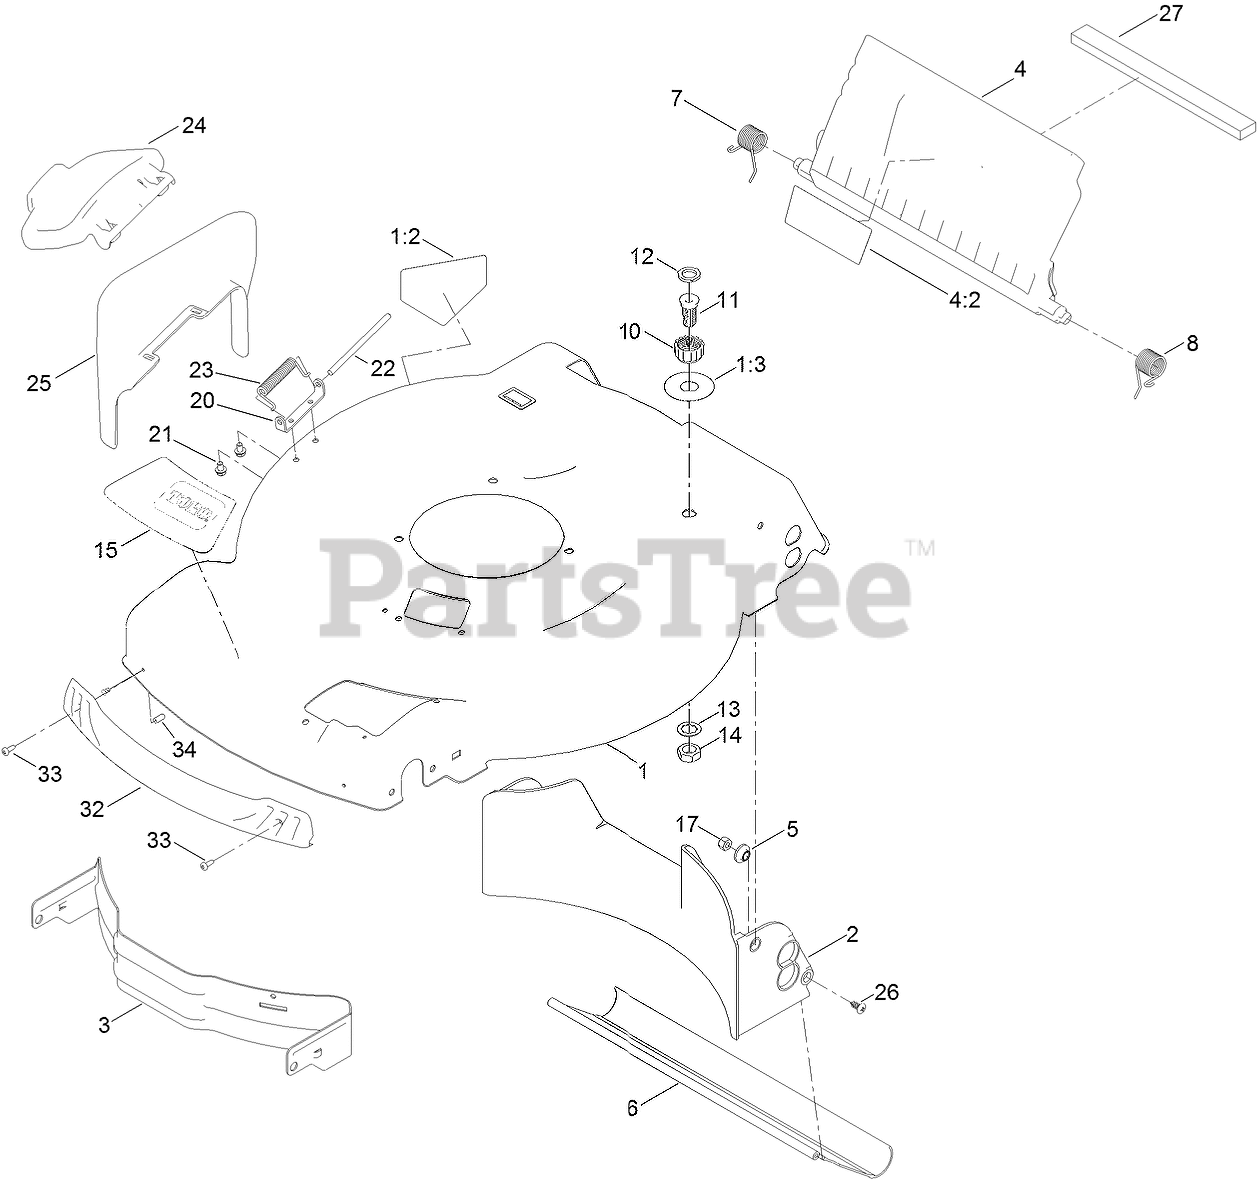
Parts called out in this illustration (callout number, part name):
1	HOUSING ASM
1:2	DECAL-DANGER
1:3	DECAL-QUICK WASH
2	BAFFLE-REAR
3	BAFFLE-FRONT
4	REAR DEFLECTOR ASM
4:2	DECAL-WARNING
5	WASHER-STEPPED, BAFFLE
6	SHIELD-TRAILING
7	SPRING-TORSION
8	SPRING-TORSION
10	COUPLING-HOSE, WASHOUT PORT
11	PORT-WASHOUT
12	WASHER-SEAL, WASHOUT PORT
13	WASHER-LOCK
14	NUT-JAM
15	DECAL-DECK
17	NUT-LOCK, NI
20	BRACKET-COVER
21	SCREW-HWH
23	SPRING-TORSION
24	DEFLECTOR-SIDE
25	CHUTE-DISCHARGE, SIDE
26	SCREW-PTH
27	FOAM-SEAL
32	BUMPER
33	SCREW-FORMING, THREAD
34	CAP-PLUG
